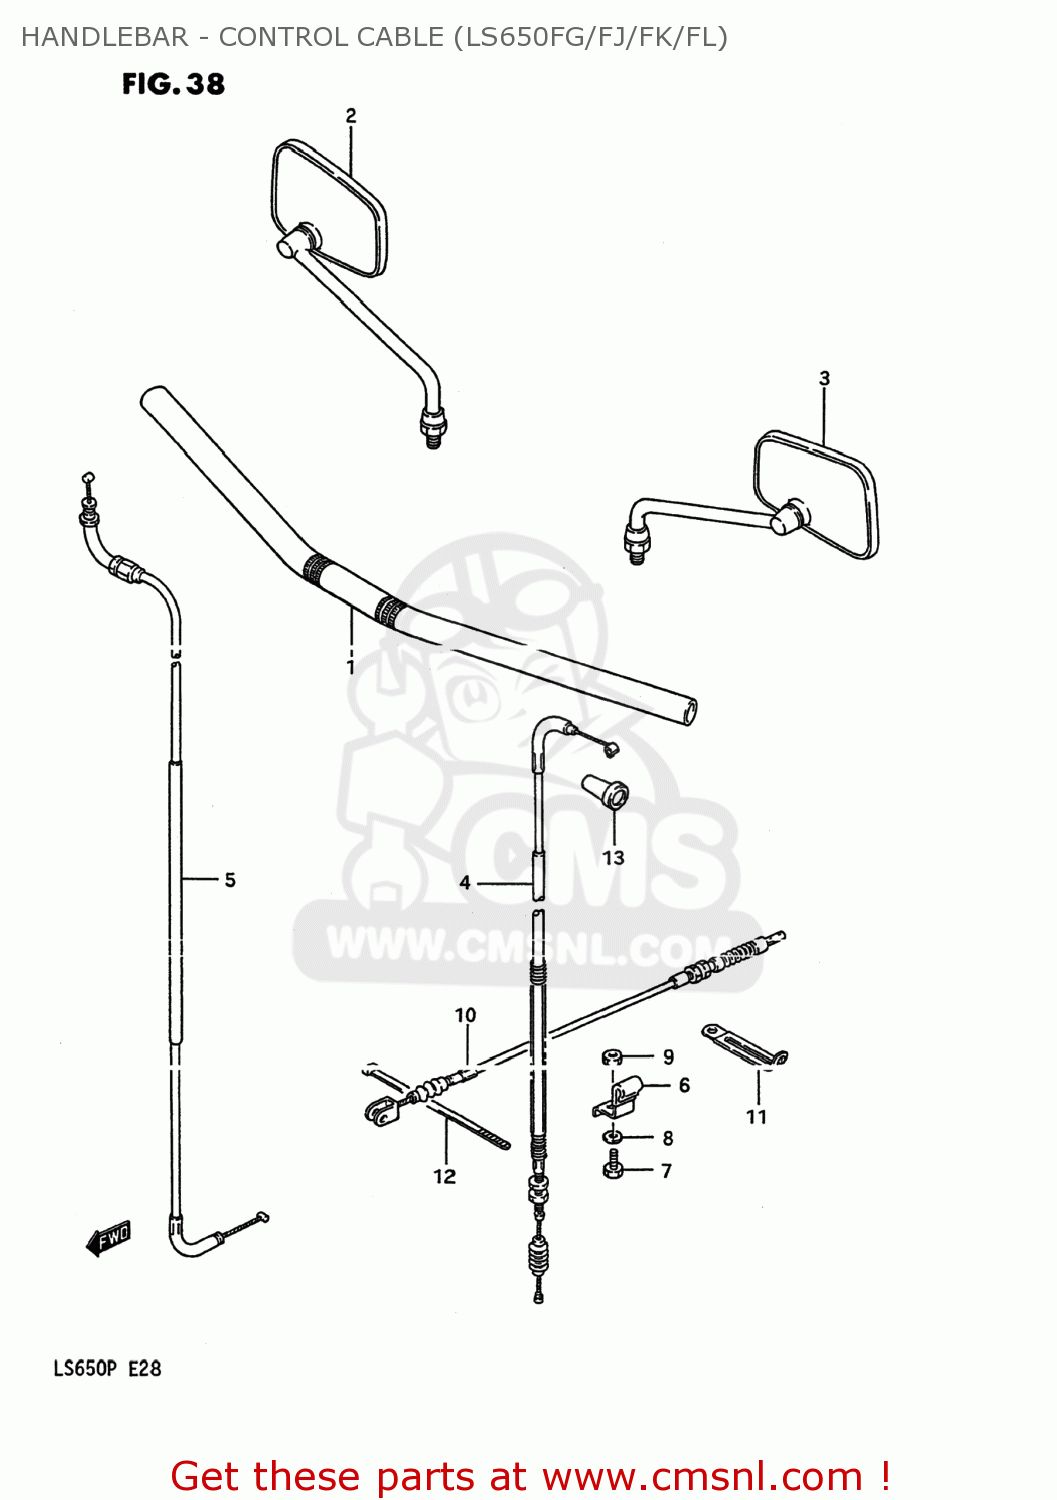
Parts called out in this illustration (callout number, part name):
1	HANDLEBAR
2	MIRROR ASSY,RR VIEW,R
3	MIRROR ASSY,RR VIEW,L
4	CABLE ASSY,CLUTCH
5	CABLE ASSY,THROTTLE
6	GUIDE,CABLE
7	BOLT 6X16
8	WASHER,LOCK
9	NUT
10	CABLE COMP,STOP LAMP SWITCH
11	CLAMP
12	CLAMP
13	BOOT,CLUTCH CABLE
